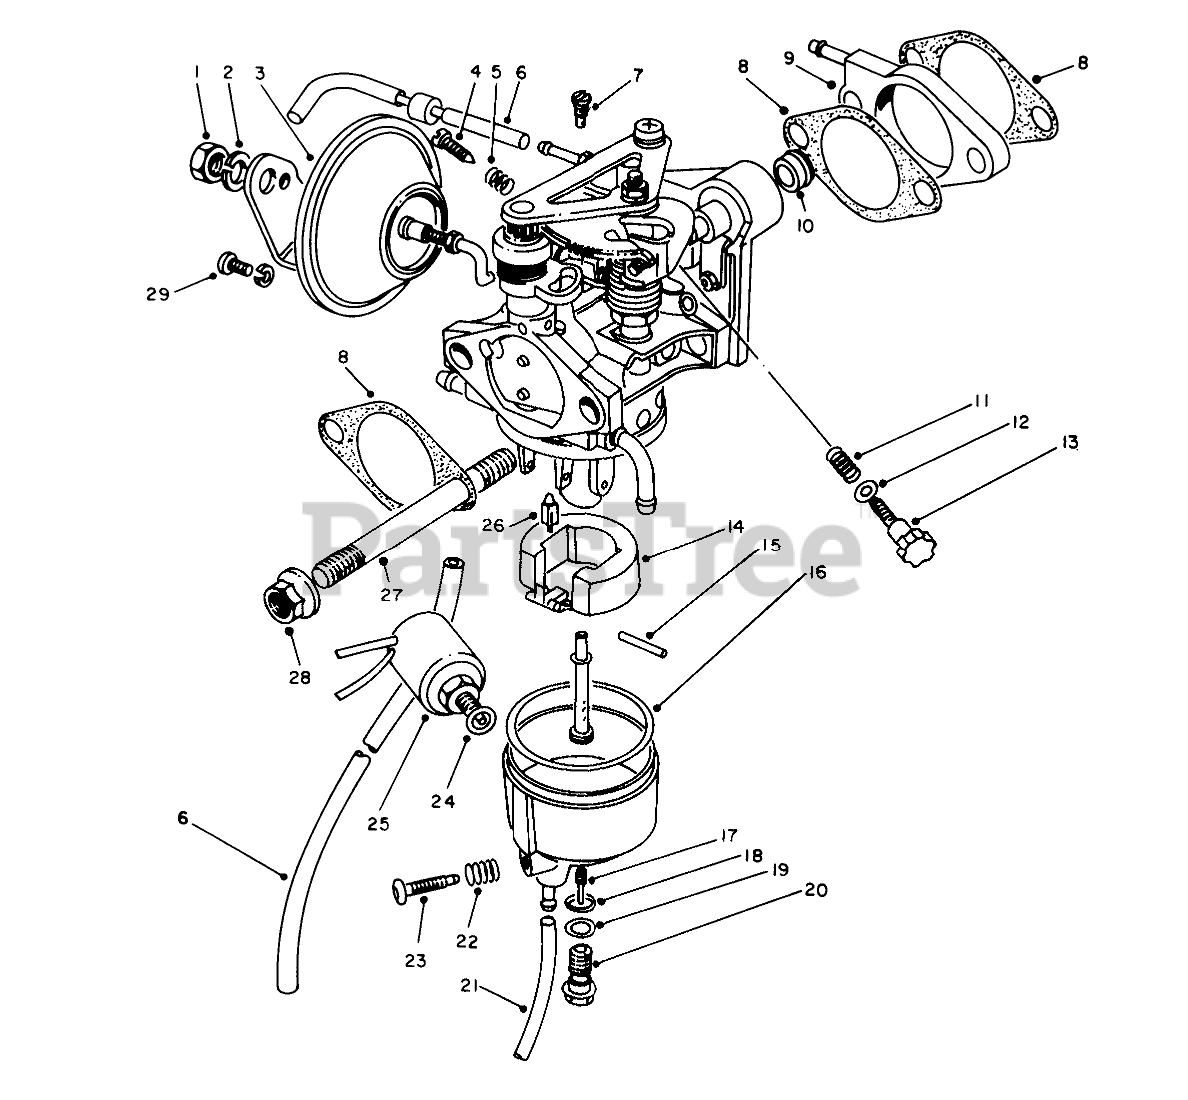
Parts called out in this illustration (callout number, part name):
2	WASHER-LOCK
3	Depression Chamber
4	Screw
5	SPRING
7	PILOT JET (65)
8	Gasket
9	CARB INSULATOR
10	Cover
11	SPRING
12	WASHER (4.2X8X0.5)
13	Screw-Idle Adjusting
14	Float
15	Pin
16	Gasket
17	Jet-Main (105)
18	0-Ring
19	Washer
20	Holder
22	Spring
23	Screw
24	Washer
25	Solenoid
26	Needle
27	Stud Bolt
29	SCREW
